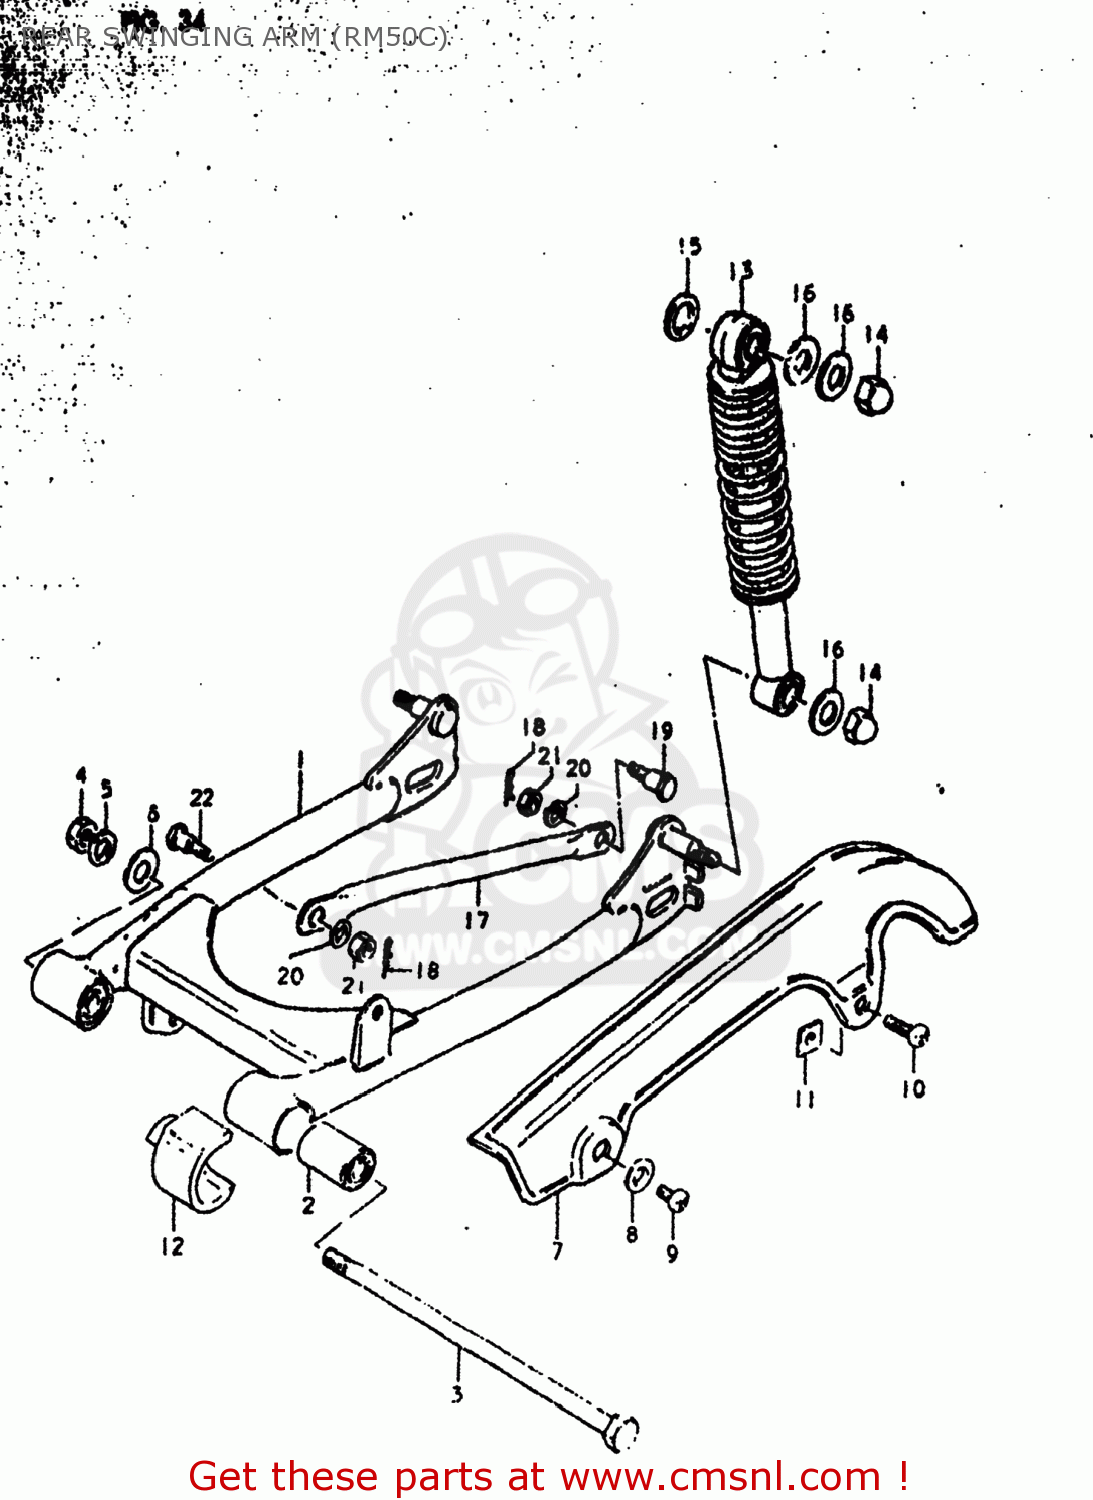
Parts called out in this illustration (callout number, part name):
1	SWING ARM ASSEMBLY,REAR
2	BUSH
3	SHAFT,REAR SWING ARM
4	NUT
5	LOCK WASHER
6	WASHER
7	CASE,CHAIN
8	WASHER
9	SCREW
10	SCREW 6X12
11	NUT,CHAIN CASE RR
12	BUFFER,CHAIN TOUCH DEFLECTOR
13	ABSORBER ASSEMBLY,REAR SHOCK
14	NUT, LOWER LH
15	WASHER
16	WASHER
17	TORQUE LINK,REAR
18	CLIP
19	BOLT(8X26.5)
20	LOCK WASHER
21	NUT
22	BOLT(8X22)
